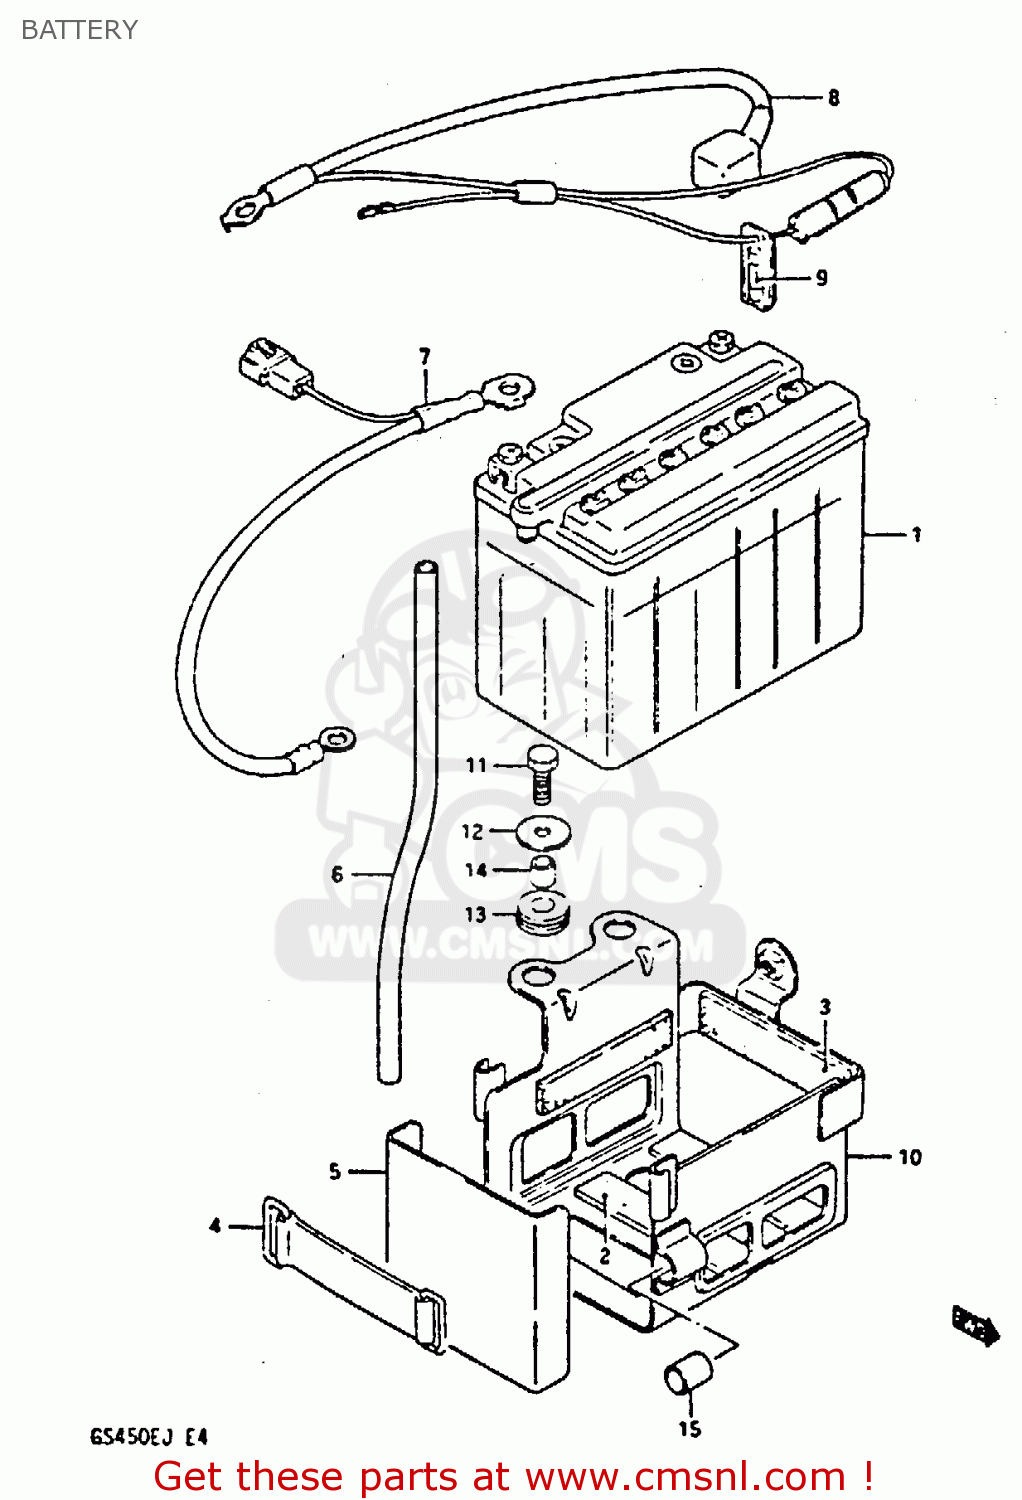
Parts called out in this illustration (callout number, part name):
1	BATTERY(YB12B-B2,12V11.6A)
2	PROTECTOR(170X95X3.0)
3	PROTECTOR,20X9
4	BAND
5	COVER,BATTERY
6	HOSE,BATTERY EXHAUST
7	WIRE,BATTERY MINUS
8	CASE ASSY,FUSE (WITH CABLE)
9	FUSE(15A)
10	HOLDER,BATTERY
11	BOLT,M6X1X20
12	WASHER
13	CUSHION
14	SPACER(6.2X9X7.5)
15	CUSHION
